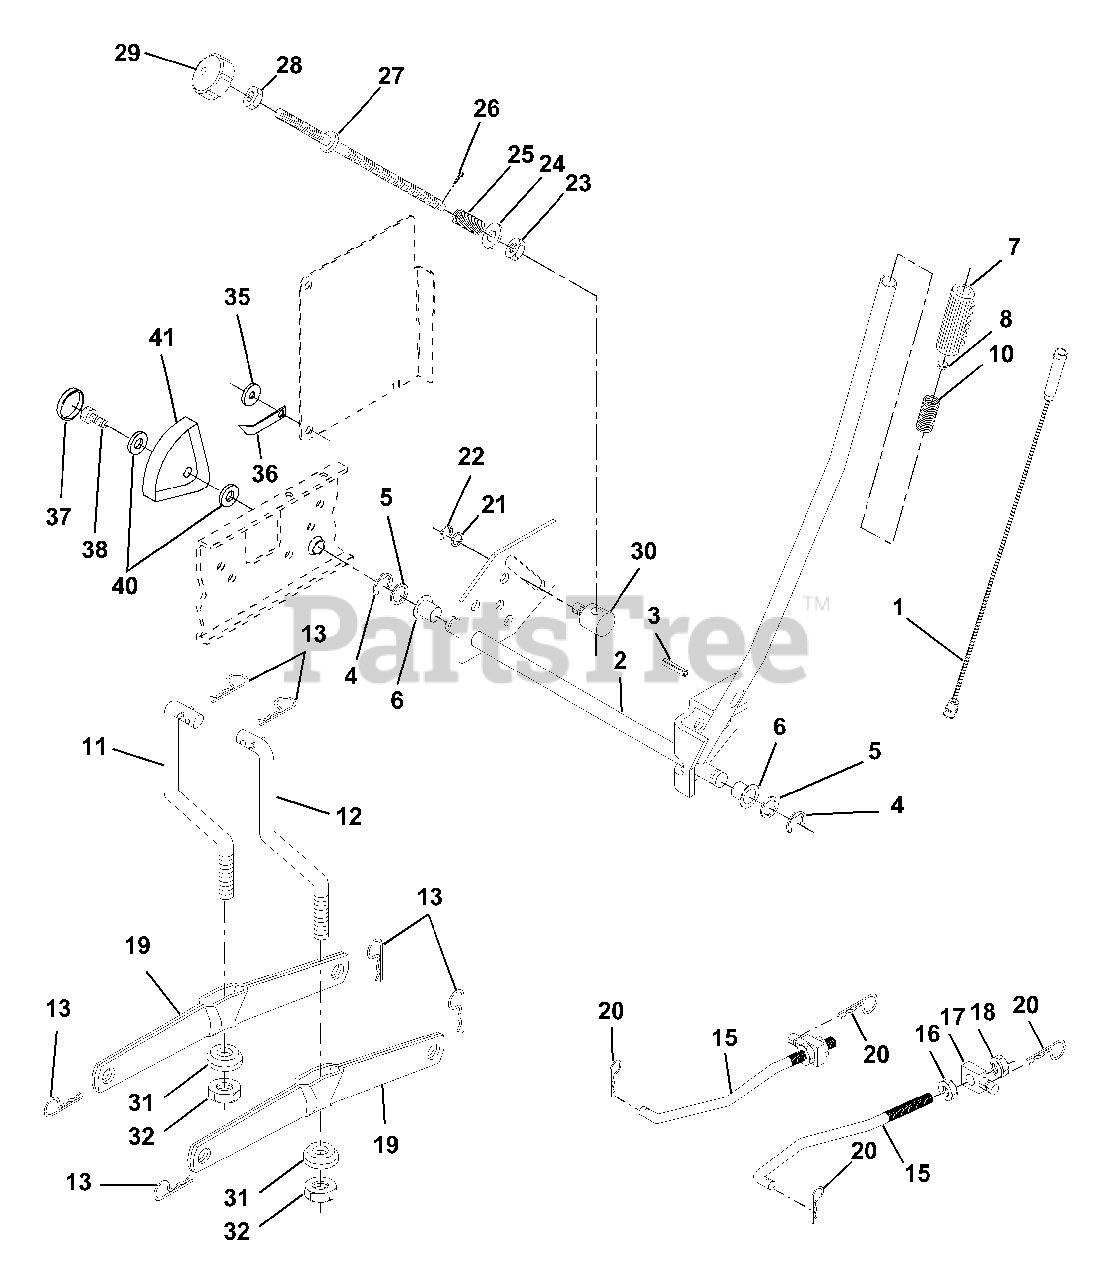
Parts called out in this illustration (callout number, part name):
1	Wire Asm Inner W/plunger 20 56
2	Shaft Asm Lift RH w/Inf W/T
3	Pin Groove 1 500 Zinc
4	E Ring #5133-62
5	Washer 21/32 X 1 X 21 Ga
6	Bearing Nylon Blk 629 Id
7	Grip Handle Fluted Blk
8	Button Plunger Black
10	Spring Cprsn 3 750 Oiled
11	Link Lift LH Fixed Length
12	Link Lift RH Fixed Length
13	Retainer Spring
15	Link Front
16	Nut Jam Hex 1/2-13 Unc
17	Trunnion Blk Zinc
18	Nut Lock W/wsh 1/2-13unc
19	Arm Suspension Rear
20	Retainer Spring
21	Washer 15/32 X 3/4 X 16 Ga
22	Ring Klip #t5304-37
23	Nut Special
24	Washer 13/32 X 5/8 X 16 Ga
25	Spring 2-1/8"
26	Pin Cotter 3/32 X 1/2
27	Rod Adj Lift Zinc 9 00 Wrk Lg
28	Nut Hex Jam 3/8-16 Unc
29	Knob Inf 3/8-16 Unc Blk W/sym
30	Trunnion Dp Stop Dbl Thds PLT
31	Bearing Pvt Lift Spherical
32	Nut Nylock 3/8 - 24
35	Washer Nylon .44 x .75 x .032
36	Pointer Pnt Height ind .505
37	Plug Hole Blk 1.485/1.515 Dia.
38	Screw Thdrol 5/16-18 x 3/4
40	Washer 11/32 x 1-1/2 10 Ga.
41	Scale Ind. Height Blk.
